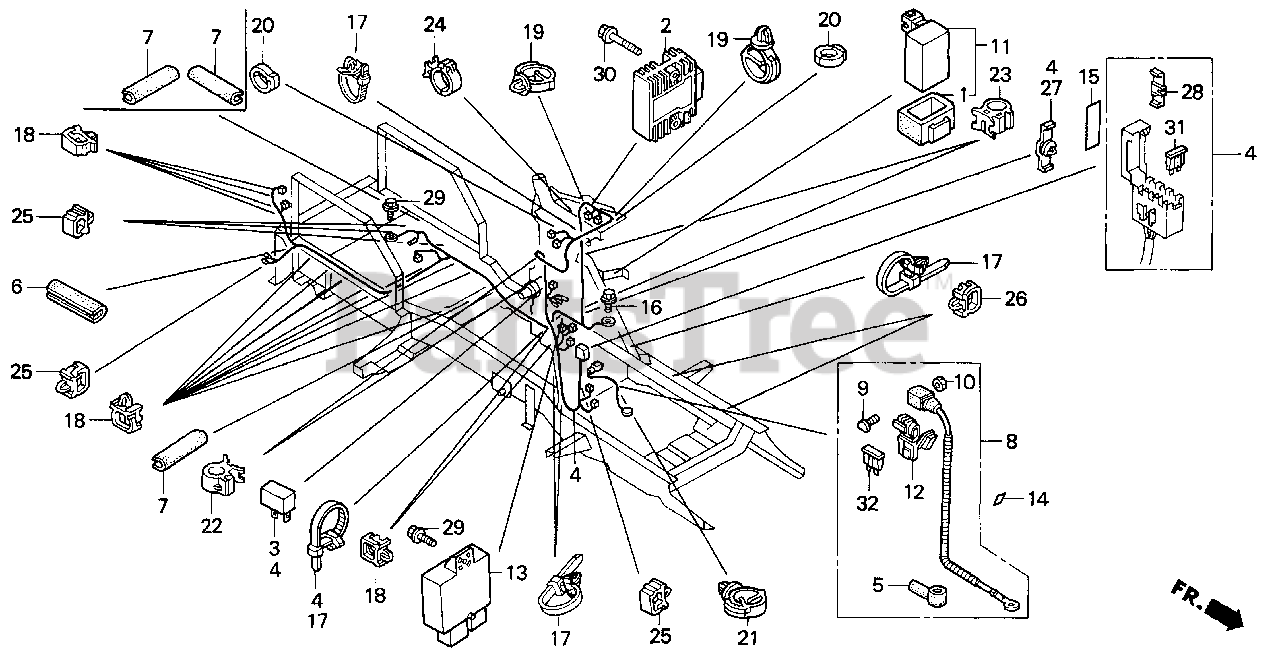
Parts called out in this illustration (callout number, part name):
1	RUBBER, IGNITION CONTROL MODULE
2	RECTIFIER ASSY., REGULATOR
2	RECTIFIER ASSY., REGULATOR (10A)
3	RECTIFIER ASSY., SILICON (STANLEY)
4	WIRE HARNESS ASSY., MAIN
5	COVER, TERMINAL
6	PROTECTOR, HARNESS
7	PROTECTOR, HARNESS
8	CABLE ASSY., STARTER
9	BOLT, BATTERY TERMINAL (SUMITOMO)
10	NUT, BATTERY TERMINAL (SUMITOMO)
11	UNIT, FUEL CONTROL (NOT AVAILABLE)
12	CASE, MAIN FUSE
13	RELAY ASSY., COMBINATION (NOT AVAILABLE)
13	RELAY ASSY., COMBINATION
14	MARK, MAIN FUSE (ENGLISH)
15	LABEL, FUSE (ENGLISH)
16	BOLT, GROUND (6X16) (SN)
17	BAND, WIRE HARNESS (WHITE)
18	CLIP, HARNESS (15MM) (BLUE)
19	CLIP, WIRE HARNESS
20	CLIP, WIRE HARNESS
21	CLIP, WIRE HARNESS (25MM)
22	CLIP, CABLE (10MM)
22	CLIP, CABLE (15MM)
23	CLIP, CABLE (15MM)
24	CLIP, CABLE (20MM)
25	CLIP, WIRE HARNESS
26	CLIP, HARNESS (7MM)
27	CLIP, WIRE HARNESS (BLACK)(HARNESS TAPING)
28	CLIP, WIRE HARNESS (BLACK)
29	BOLT, FLANGE (6X12)
30	BOLT, FLANGE (6X20)
31	FUSE, BLADE (5A)
32	FUSE, BLADE (20A)
